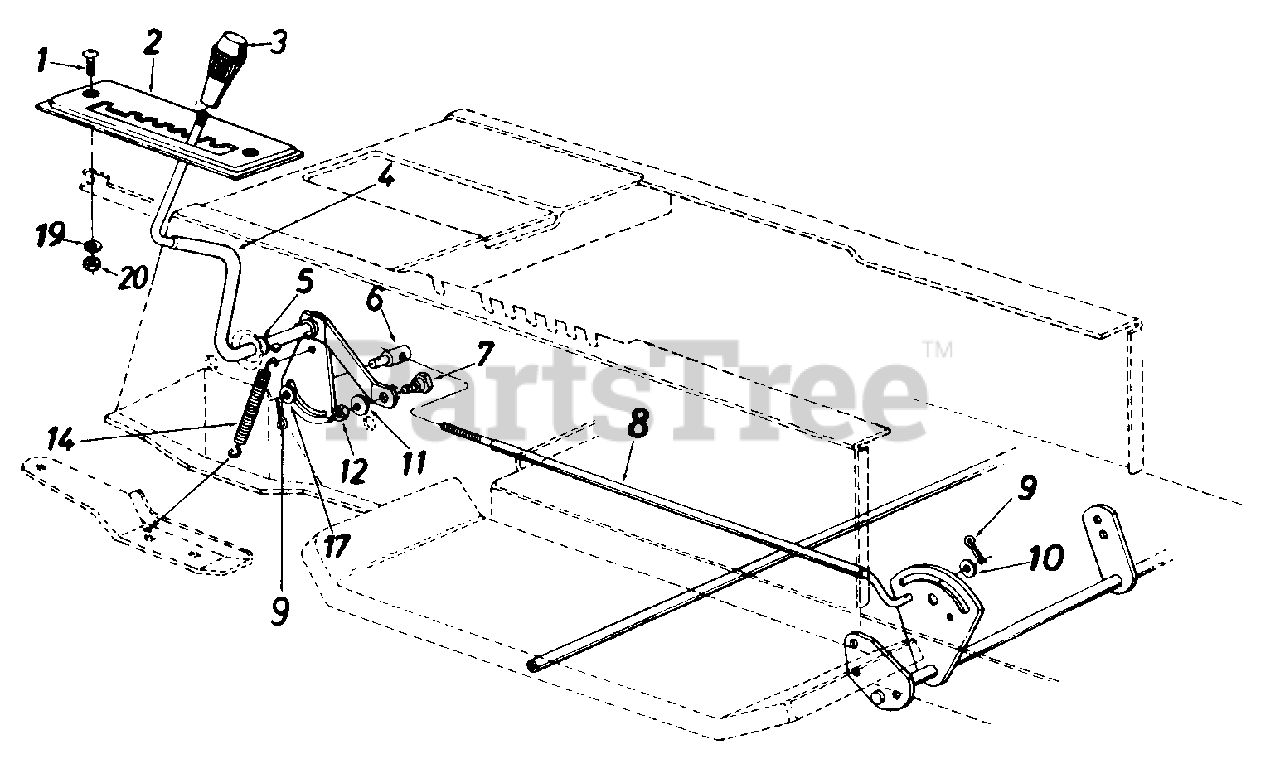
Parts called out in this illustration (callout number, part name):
1	Truss Mach. Scr. 1/4-20 x .75" Lg.
4	Speed Selector Cam Ass'y.
5	Flat Washer .53" I.D. x .93"
6	Ferrule 3/8-24 x .37" Dia.
7	Shoulder Bolt
8	Speed Control Link
9	Cotter Pin 3/32" Dia. x 1.0"
10	Fl-Wash. .469" I.D. x .88"
11	L-Wash. 5/16" I.D.
12	Hex Nut 5/16-18 Thd.
14	Spring .38" O.D. x 3.18" Lg.
17	Fl-Wash. .385" I.D. x .62"
19	L-Wash. 1/4" I.D.
20	Hex Nut 1/4-20 Thd.
